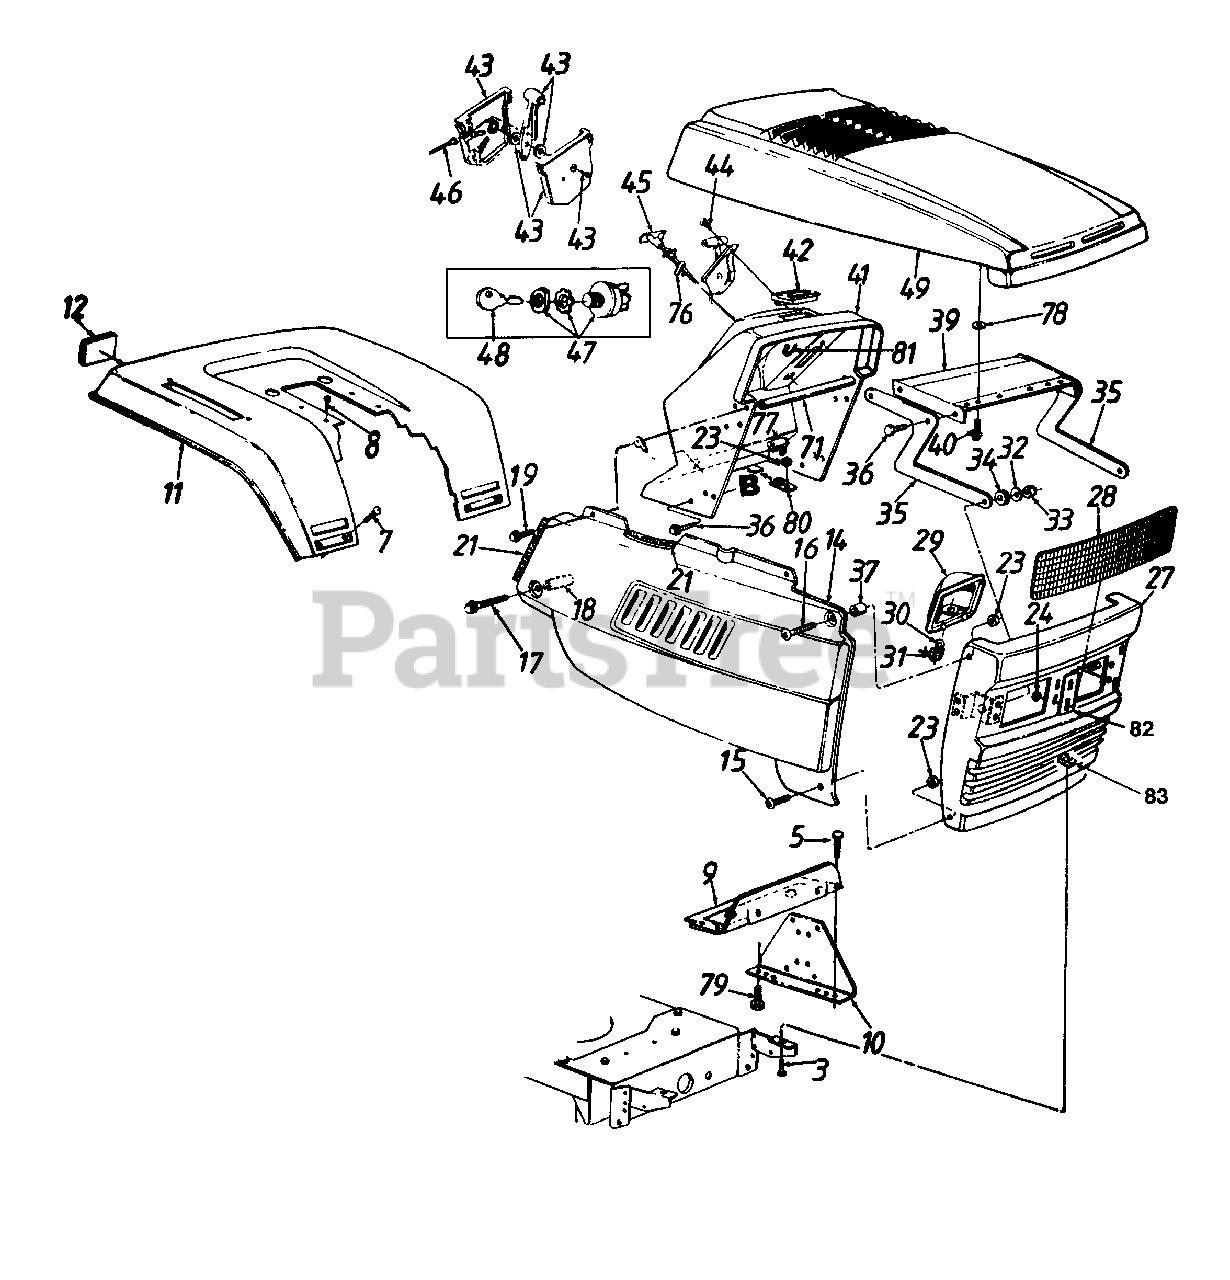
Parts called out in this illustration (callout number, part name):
3	Hex Bolt 5/16-18 x .75" Lg.
5	Hex Wash. Hd. Scr. 5/16" x .5" Lg.
7	Carriage Bolt 1/4-20 x .5" Lg.
8	Hex Wash. Hd. Tap Scr. 5/16 x .75" Lg.
16	Truss Mach. Scr. 1/4-20 x 1.0" Lg.
17	Hex Wash. TT-Tap Scr. 1/4-20 x 1.75" Lg.
18	Spacer .26" I.D. x 1.32"
19	Hex Rolling Tap Scr. 1/4-20 x .75" Lg.
21	Trim Strip - 18" Lg.
23	Hex Sems Nut 1/4-20 Thd.
24	Speed Nut 5/16" Thd.
29	Headlamp Housing
30	Headlamp
31	Twist Lock Lamp Socket
32	Bell-Wash. .345" I.D. x .88"
33	Hex L-Nut 5/16-18 Thd.
34	Rubber Washer
37	Spacer .262" I.D. x .31"
41	Dash
42	Ammeter
43	Throttle Control Box Ass'y.
44	Mach. Scr. #10 x .44" Lg.
45	Choke Control 23" Lg.
46	Throttle Control Wire 18.5" Lg.
47	Ignition Switch
48	Ignition Key
49	Hood - Red
71	Grille Support Tube
76	Choke Retainer
77	Light Switch
78	Fl-Wash. .406" I.D. x .812" O.D.
79	Hex Bolt 1/4-20 x .88" Lg
80	Dash Fastening Tab
81	Cable Tie
82	Chrome Label
83	U-Nut 5/16-18 Thd.
